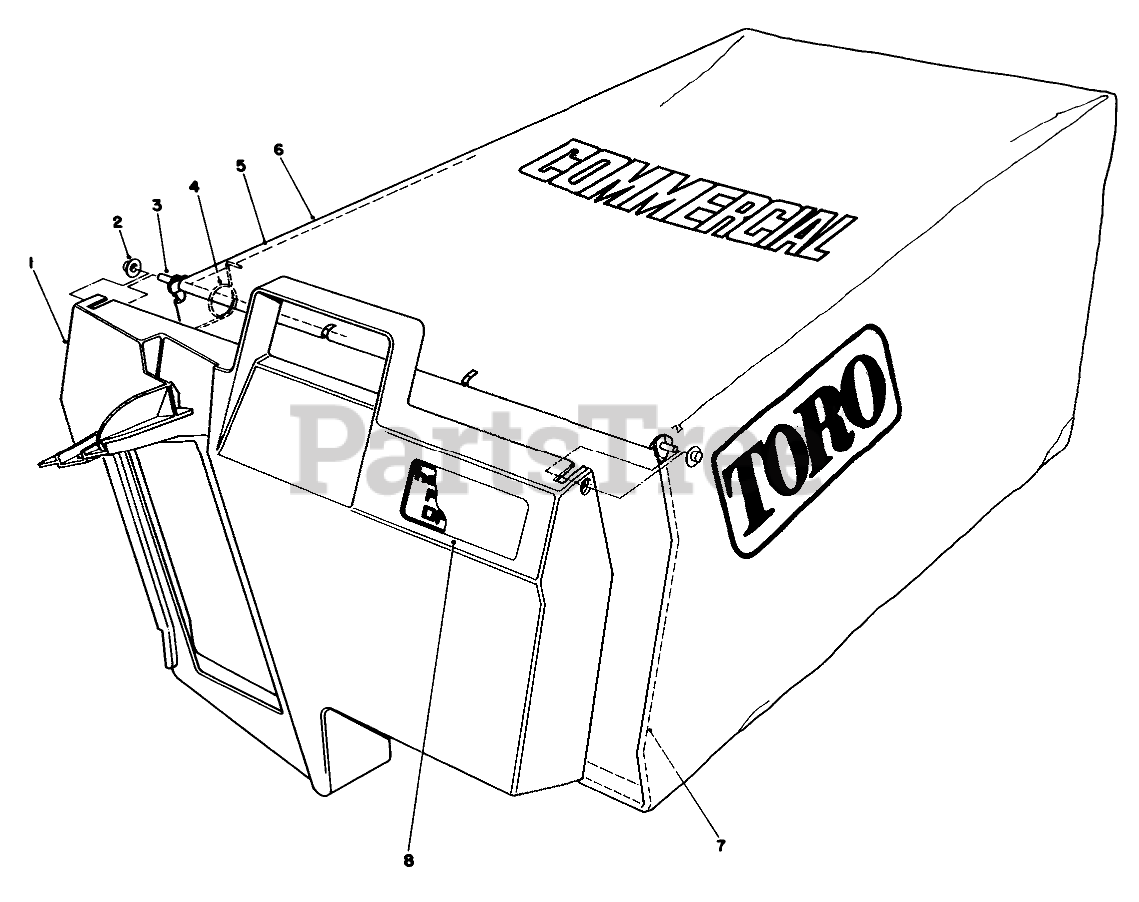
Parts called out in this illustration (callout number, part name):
1	Door-Grass Bag
2	NUT-PUSH
3	HINGE-DOOR, BAG
4	SPRING
5	FRAME-BAG, UPPER
6	Bag-Grass
7	FRAME-BAG
8	Decal-Bag Door
